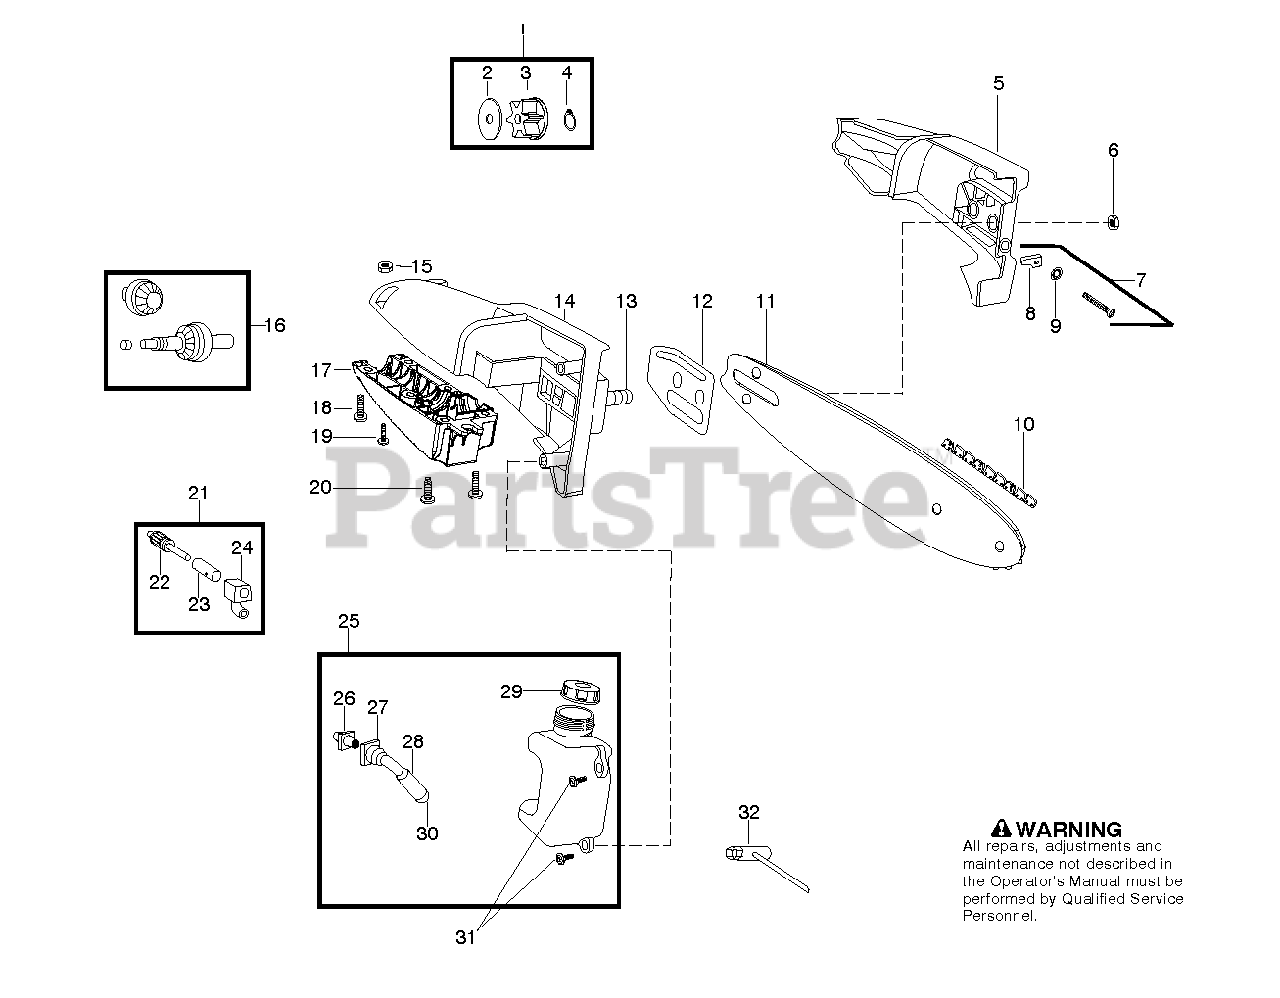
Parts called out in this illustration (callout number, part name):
1	SPROCKET
3	SPROCKET
4	RING SPROCKET RETAINER
5	BAR CLAMP ASSY
7	RETAINER
8	ADJUST PIN,BAR 36/41
9	RETAINER
10	CHAIN
12	PAD BAR PLATE
14	GEAR HOUSING UPPER
16	KIT GEAR ASSY
17	GEAR HOUSING LOWER
18	SCR 10-24 MS LDK PAN PH
19	SCREW-10-14 X 1/2 PLASTITE
20	SCREW-10-14 X 13/16 (PL
22	ASSY GEAR PLUNGER
24	OIL BLOCK ASSY
25	ASSY OIL TANK PRUNER ATTACH
26	OIL PUMP FITTING
27	LINE OIL INTAKE
28	FILTER
29	CAP OIL
30	PLUG
32	WRENCH-BAR
